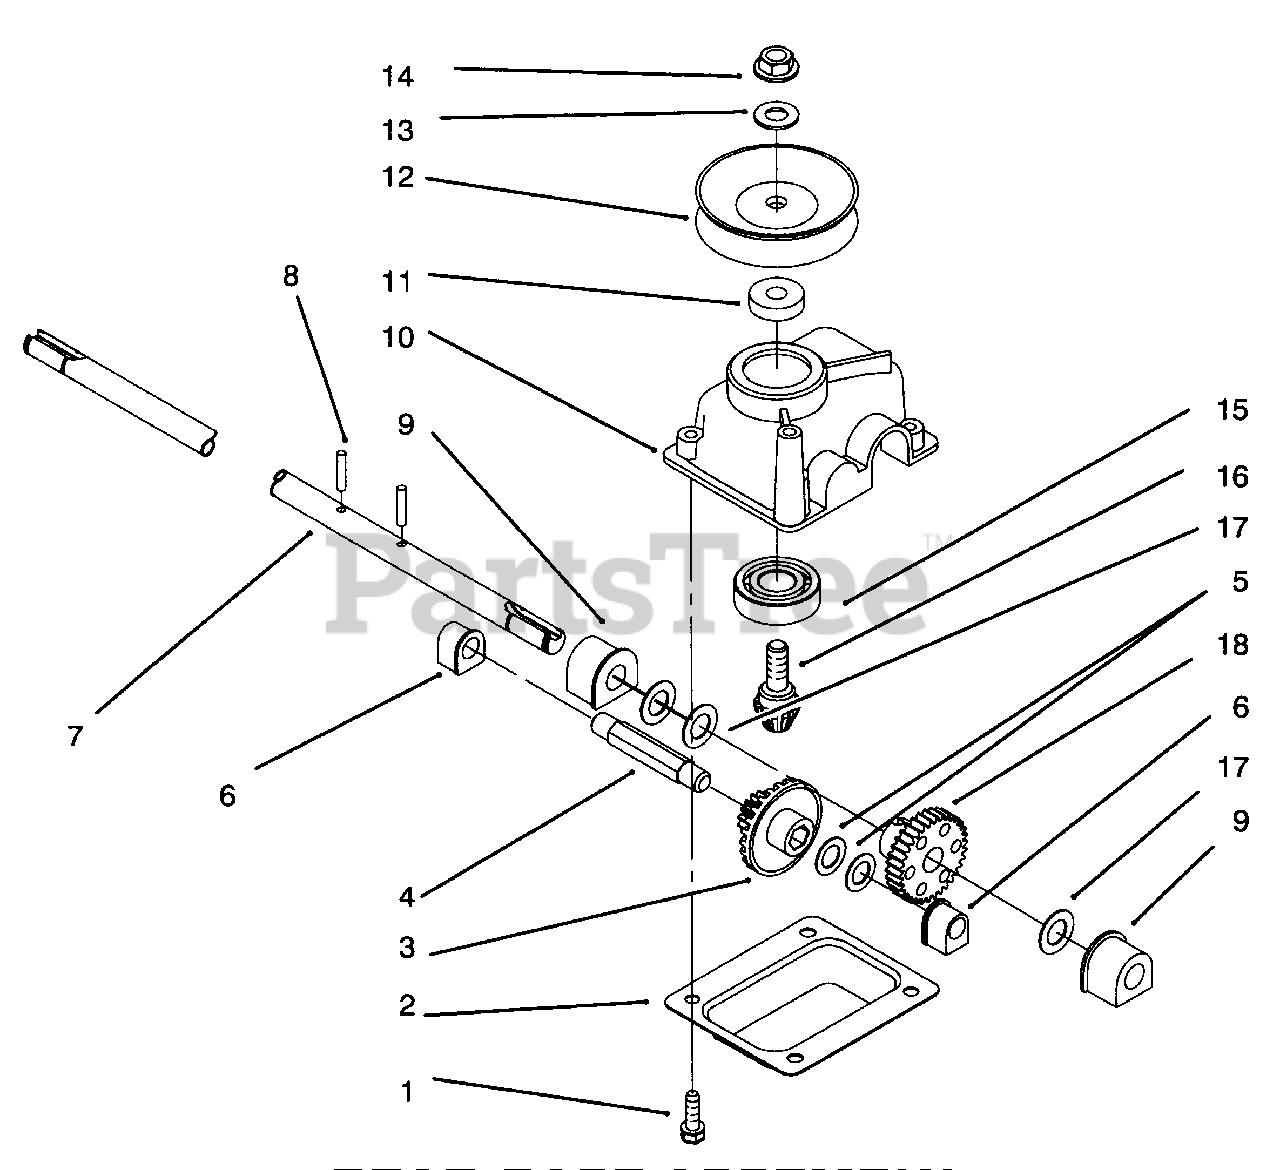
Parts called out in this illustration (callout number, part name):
1	Screw-Tapping
2	Cover-Gear Case
3	Pinion-15 Tooth
4	Shaft-Intermediate
7	Shaft-Output
8	Pin-Groove
9	Bushing-Output
10	Case-Gear
12	Pulley-Half
14	Nut-Lock
15	Bearing-Ball
16	Gear-Bevel Pinion
17	Washer-Thrust
18	Gear-34 Tooth
